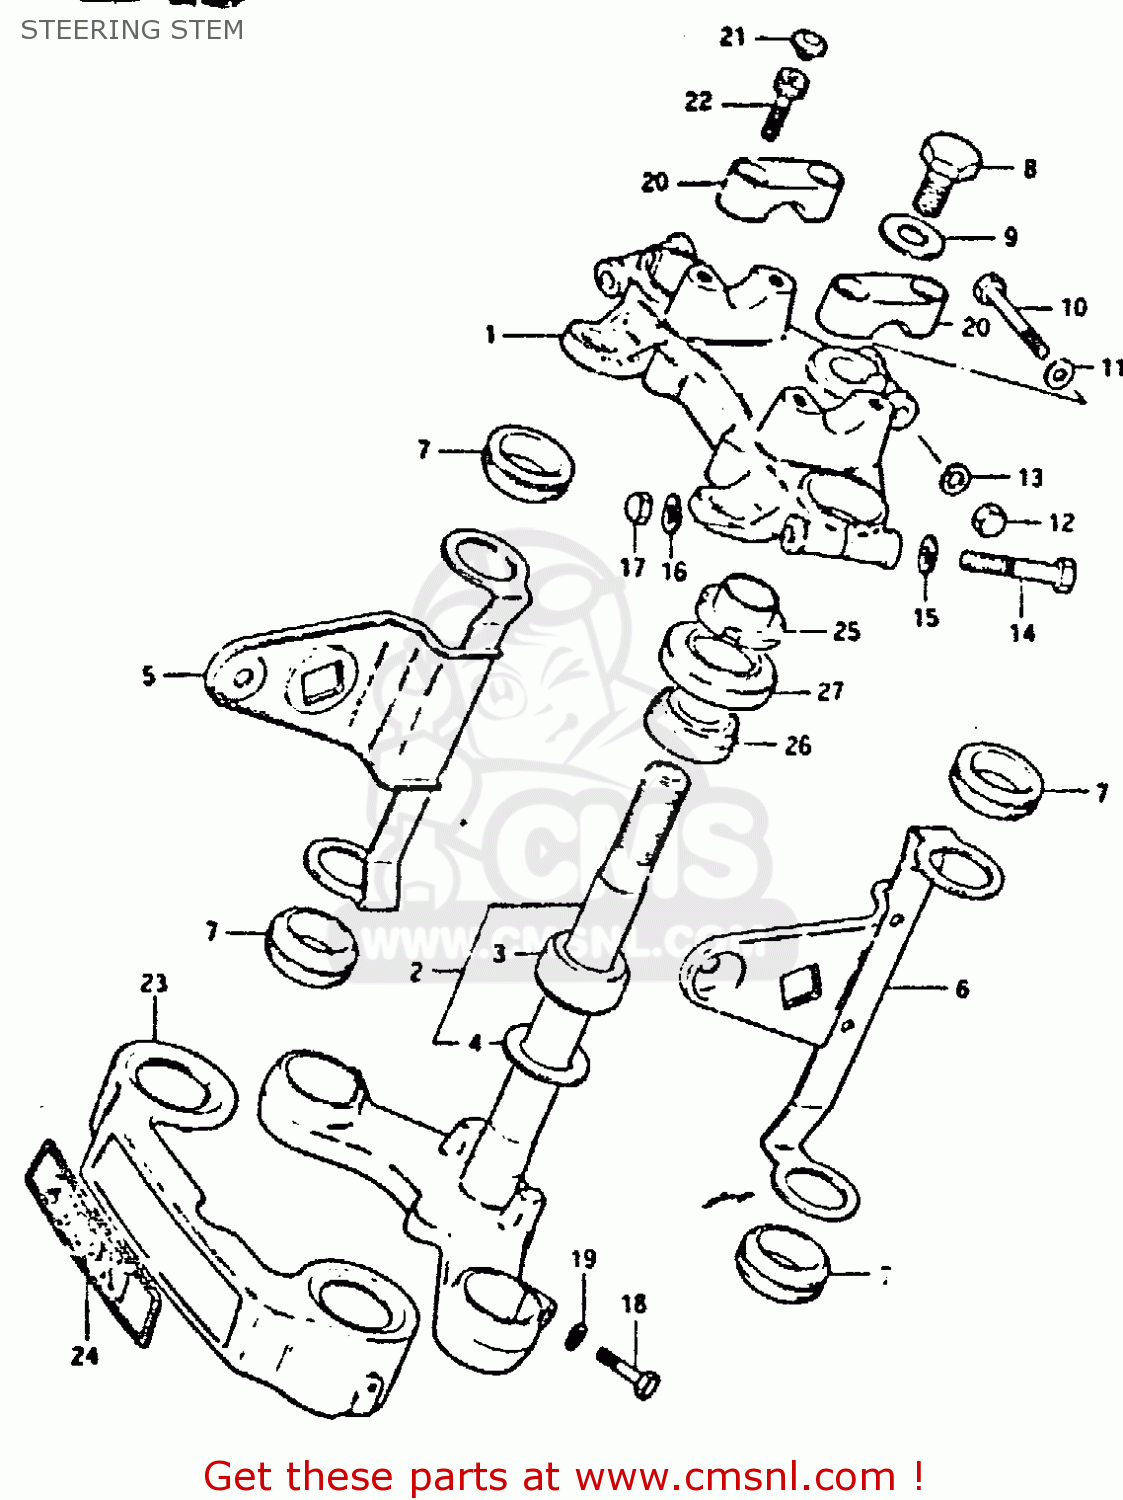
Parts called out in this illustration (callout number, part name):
1	STEM HEAD, STEERING (BLACK)
2	STEM,STEERING
3	BEARING
4	WASHER,THRUST
5	BRACKET, HEADLAMP RH (BLACK)
6	BRACKET, HEADLAMP LH (BLACK)
7	CUSHION,HEADLAMP BRACKET
8	BOLT,STEERING STEM HEAD
9	WASHER
10	BOLT 8X50
11	WASHER
12	NUT,M8X1.25X12
13	LOCK WASHER
14	BOLT 10X55
15	WASHER
16	LOCK WASHER
17	NUT
18	BOLT 10X40
19	LOCK WASHER
20	HOLDER,HANDLEBAR(BLACK)
21	CAP(OD:14.5)
22	BOLT, REAR (8X30)
23	COVER,FRONT FORK
24	EMBLEM
25	NUT,STEERING STEM
26	TAPER,ROLLER BEARING
27	DUST SEAL,STEERING UPR
